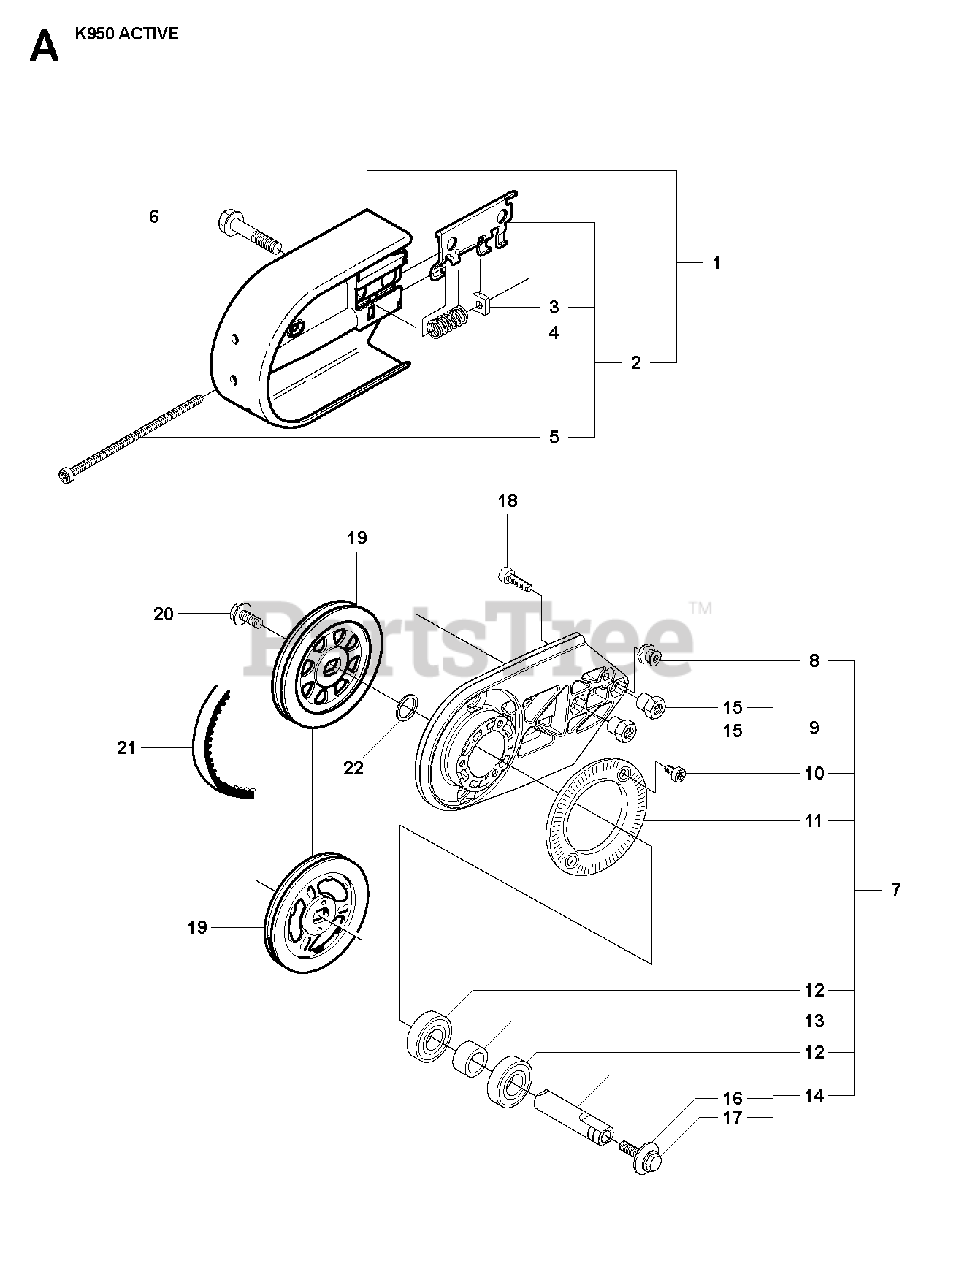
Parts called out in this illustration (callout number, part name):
1	BELT GUARD"16"". Incl. 2"
1	BELT GUARD"12"", 14"". Incl. 2"
2	BELT TENSIONER ASSYIncl. 3, 4, 5
4	COMPRESSION SPRING
7	BEARING HOUSINGIncl. 8, 9, 10, 11, 12, 13, 14
8	TORSION STOP
9	BEARING HOUSINGIncl 15
10	SCREW IHSCFM
12	BALL BEARING
14	SHAFTIncl. 16,17
19	PULLEY"16"""
19	PULLEY"12"", 14"""
